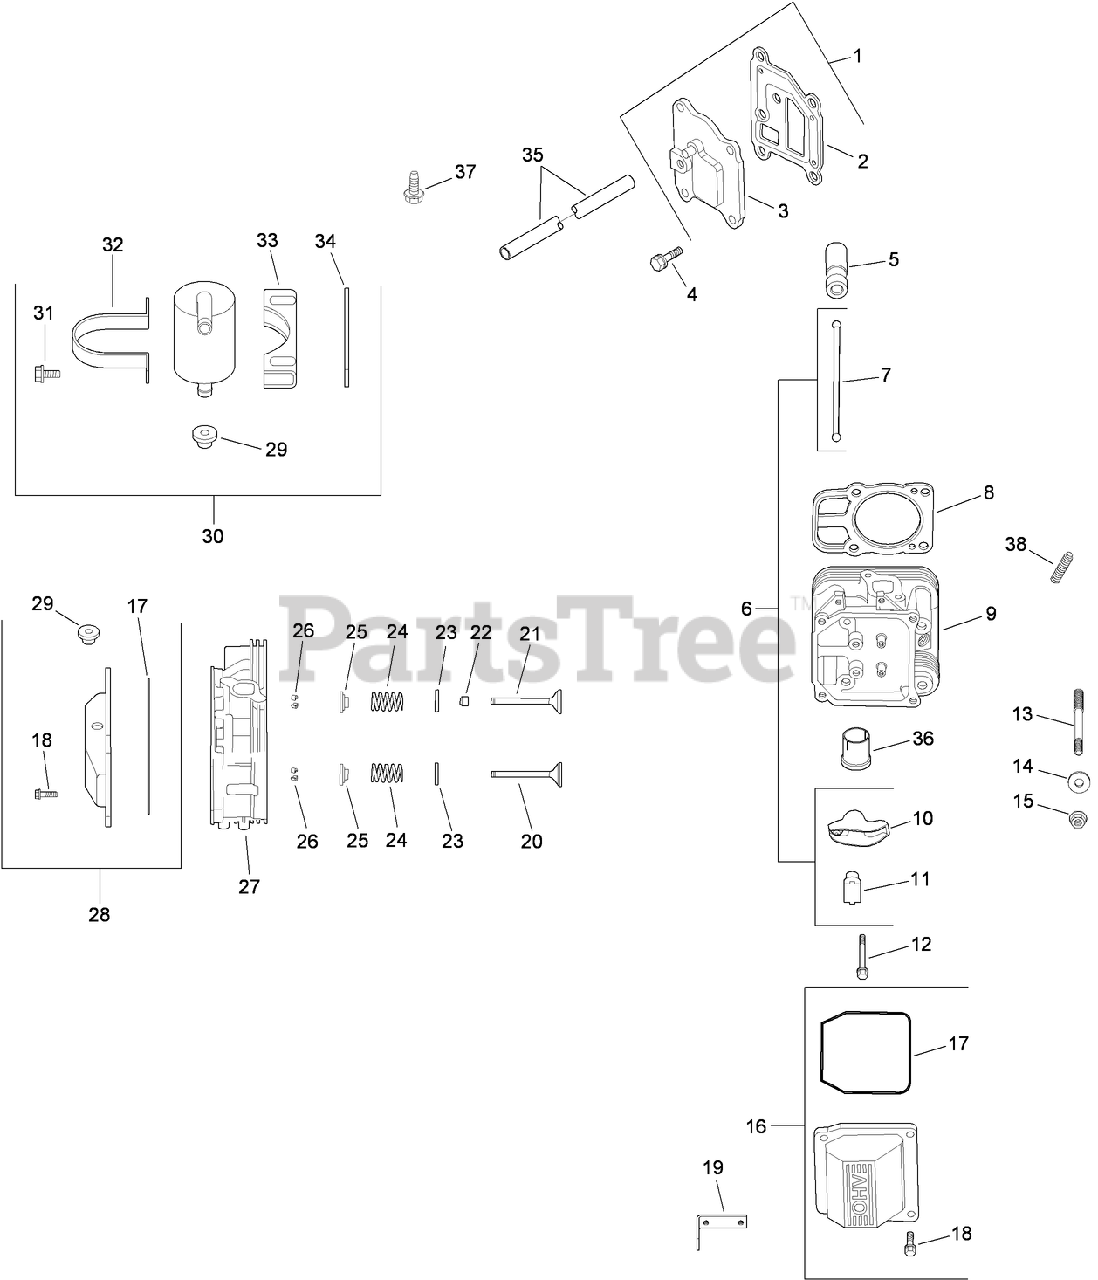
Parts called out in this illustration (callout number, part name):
1	breather cover w/gasket Kit (INCLUDES 2, 3)
2	GASKET-BREATHER
3	Cover-Breather
4	SCREW-HHFTF (M6X1.0X20)
5	HYDRAULIC VALVE LIFTER KIT (INCLUDES 25 357 14-S)
6	VALVE TRAIN KIT (INCLUDES 7, 10, 11)
7	ROD-PUSH
8	CYLINDER HEAD GASKET KIT
9	HEAD-CYLINDER (No.2) (INCLUDES 38)
10	ARM-ROCKER
11	PIVOT-ARM, ROCKER
12	SCREW-FLANGE (M6X1.0X34)
13	STUD (M8X1.25xM10X1.5x105MM)
14	WASHER-FLAT (8.6 MM)
15	NUT-FLANGE (M8X1.25)
16	PLAIN ROCKER COVER KIT (INCLUDES 17, 18)
17	O-RING (VALVE COVER)
18	SCREW-FLANGE (M6X1.0X30)
19	STRAP-LIFTING
20	VALVE-EXHAUST (STD)
20	VALVE-EXHAUST (.25)
21	VALVE-INTAKE (STD)
21	VALVE-INTAKE (.25)
22	SEAL-STEM, VALVE
23	RETAINER-SPRING
24	SPRING-VALVE
25	CAP-SPRING, VALVE
26	RETAINER KIT
27	HEAD-CYLINDER (No.1) (INCLUDES 38)
28	BREATHER VALVE COVER ASM (INCLUDES 17, 18, 29)
29	GROMMET-RUBBER
30	BREATHER VALVE COVER KIT (INCLUDES 29, 31-34)
31	SCREW-FLANGE, THREAD FORMING (M5X0.8X16)
32	STRAP-BREATHER
33	BRACKET-SEPARATOR, BREATHER
34	Spacer
35	Hose-Breather
36	Liner-Port, Exhaust
37	SCREW-FLANGE, THREAD FORMING (M6X1.0X16)
38	STUD (M8X1.25X33)
